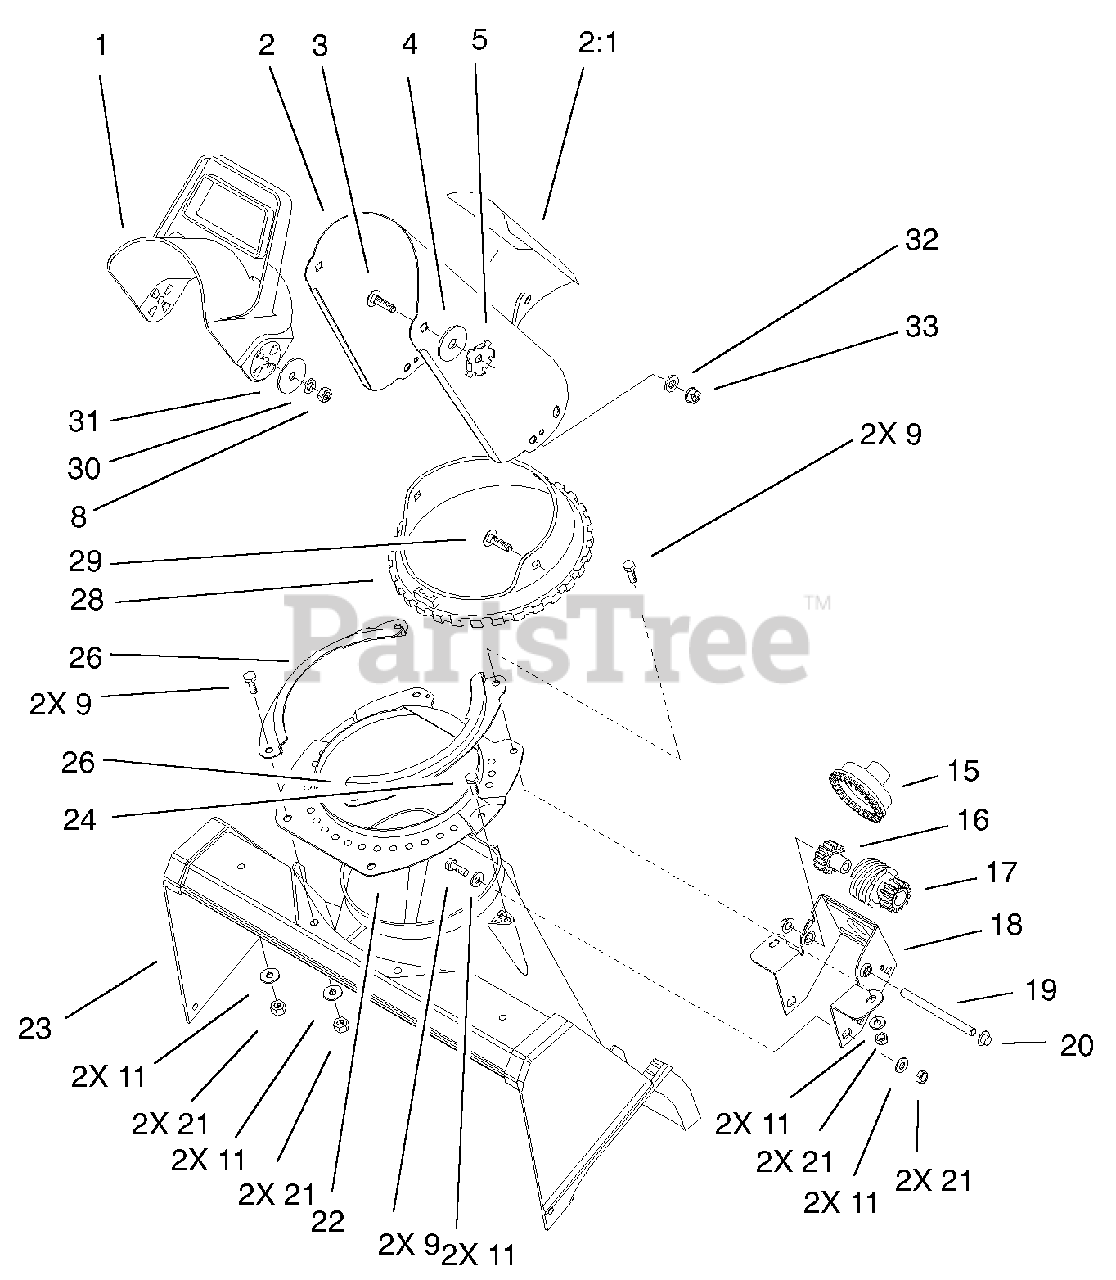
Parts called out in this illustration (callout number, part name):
1	CHUTE-DEFLECTOR
2	CHUTE ASM
2:1	DECAL-DANGER
3	SCREW-CARR
4	WASHER-RUBBER
5	PLATE-FRICTION
8	NUT-LOCK, NI
9	SCREW-HH
11	WASHER-FLAT
15	GEAR-FACE
16	GEAR-SPUR, SPACER
17	GEAR-SPUR/WORM
18	BRACKET-GEAR, CHUTE
19	SHAFT-GEAR, WORM
21	NUT-LOCK, NI
22	RING-SUPPORT, CHUTE
24	SCREW-PLASTITE
26	RING-RETAINER, CHUTE
28	RING-GEAR, CHUTE
29	SCREW-TRUSS HD, PHILLIPS
30	WASHER-BELLEVILLE
31	WASHER-FLAT
32	WASHER-FLAT
33	NUT-LOCK, NI
